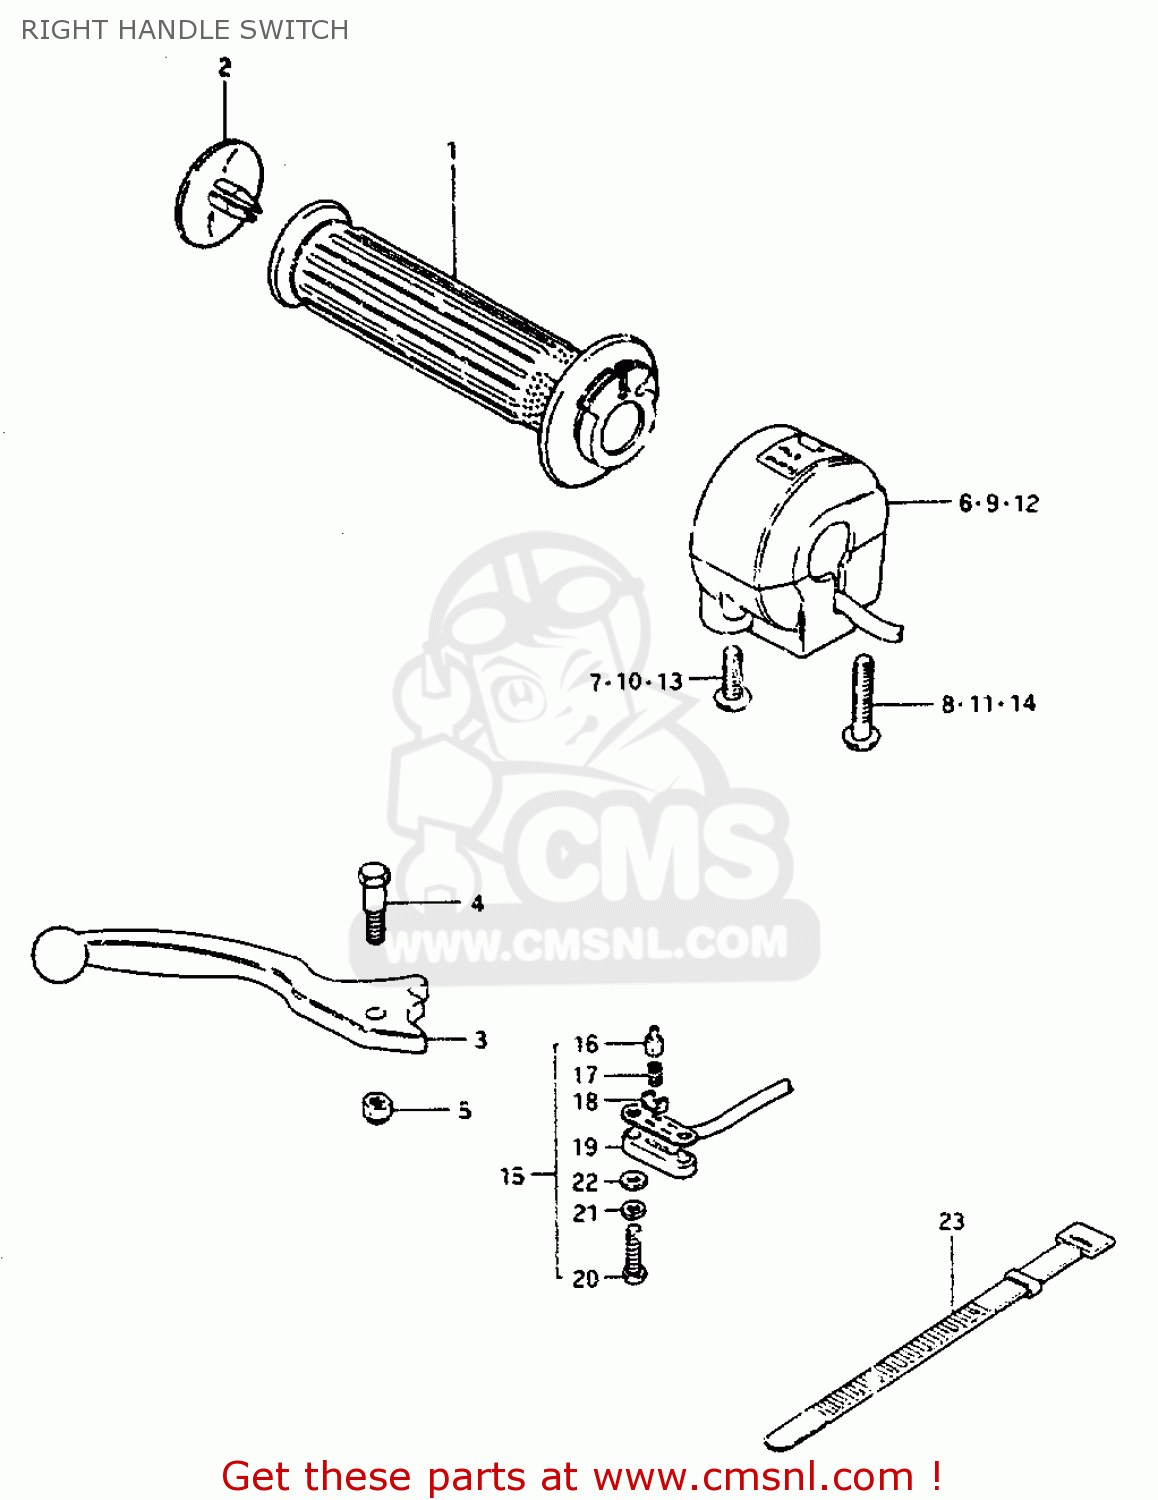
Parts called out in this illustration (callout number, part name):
1	GRIP,THROTTLE
2	CAP,GRIP END
3	LEVER,BRAKE
4	BOLT
5	NUT 6MM
6	SWITCH ASSEMBLY,HANDLE,RIGHT
7	SCREW
8	SCREW
9	SWITCH ASSY, HANDLE RH
10	SCREW
11	SCREW
23	CLAMP(L:120)
